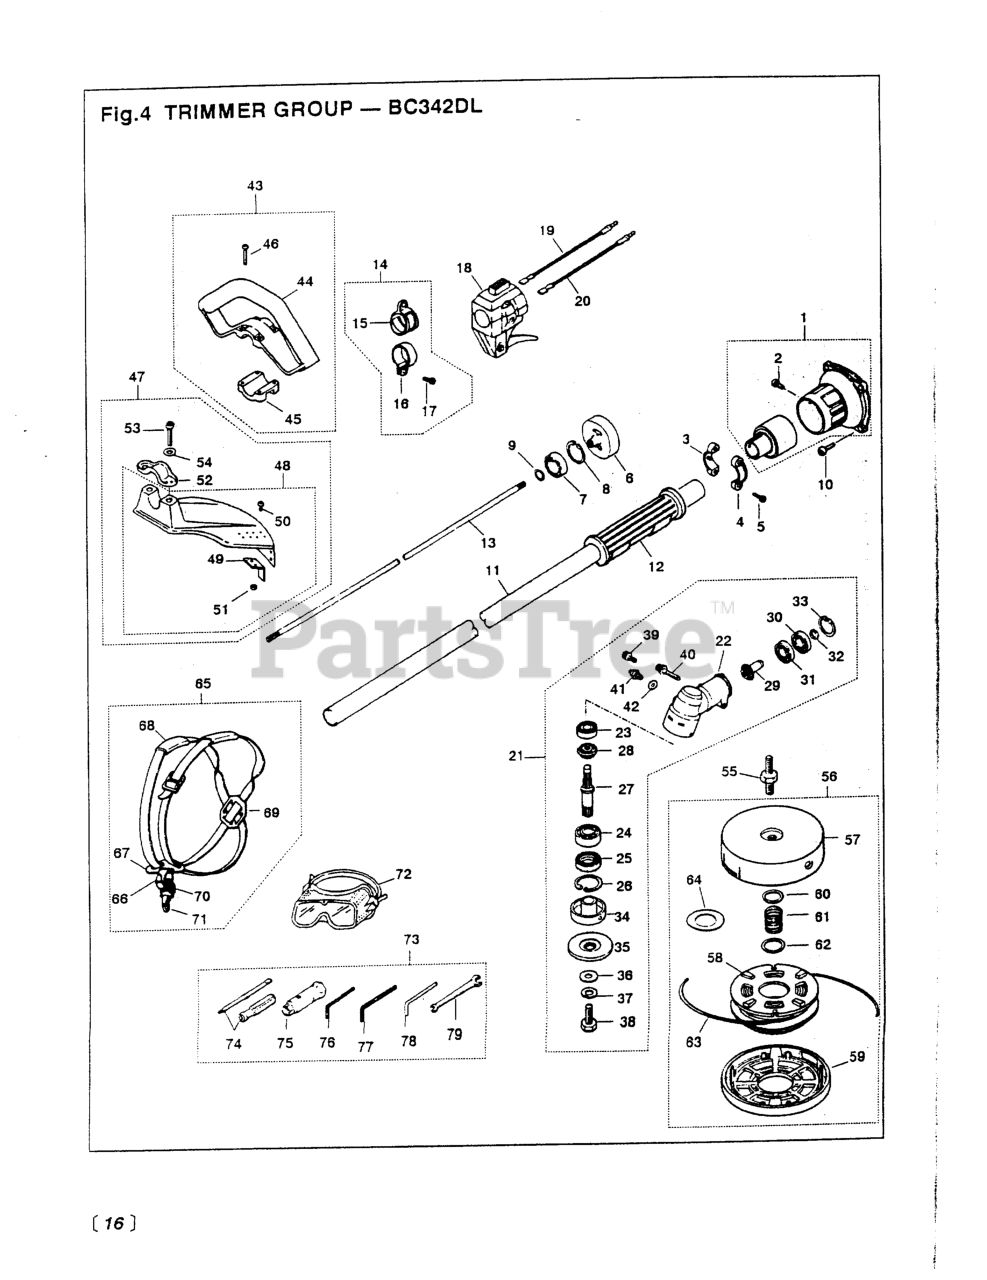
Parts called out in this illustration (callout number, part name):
1	HOUSING ASSY (RPLS-11100)
2	SCREW, M6 x 10
3	CLAMP, RIGHT (RPLS -11130)
4	CLAMP, LEFT (RPLS-11140)
5	BOLT
6	DRUM, CLUTCH
7	BEARING
8	RING, SNAP, M35 X 1.5
9	RING, SNAP, M15 X 1.0
10	BOLT, M6 X 20
13	SHAFT, SPLINE
14	HANGER ASSY. (NLA)
15	HANGER
16	CLAMP
17	SCREW, M5 x 25
19	CORD-A, BLACK
20	CORD-B, RED
21	GEARCASE (RPLS-13005)
22	GEARCASE (RPLS -13113)
23	BEARING (RPLS T3403-13510)
25	SEAL, OIL
26	RING, SNAP, M32 x 1.2
27	SHAFT, GEAR
28	GEAR, BEVEL
31	BEARING (RPLS T3403-13510)
32	RING, SNAP
34	HOLDER (A)
35	HOLDER (B)
36	WASHER, M8 x 2.3 (RPLS -20823)
37	WASHER (RPLS 3180-13270)
38	BOLT, LH
39	BOLT, M5 X 10
40	BOLT, M6 x 1.35
41	FITTING, GREASE
42	WASHER, M6 X .8
43	HANDLE ASSEMBLY
44	HANDLE
45	CLAMP
46	SCREW, M5 x 35
47	GUARD ASSY (RPLS -24001)
48	GUARD COMP.
49	BLADE
50	SCREW, M5 x 12
51	NUT
52	CLAMP
53	BOLT, M6 x 1.30
54	WASHER, M6 X 15
55	ARBOR, 8MM
56	6
59	COVER
60	PLATE, LARGE
62	PLATE, SMALL
63	CORD
64	SPACER
68	PROTECTOR
73	TOOL SET
74	SCREWDRIVER
76	WRENCH (TOOL)
77	WRENCH (TOOL)
78	BAR
79	SPANNER, 8 X 10 (RPLS 2540- )
